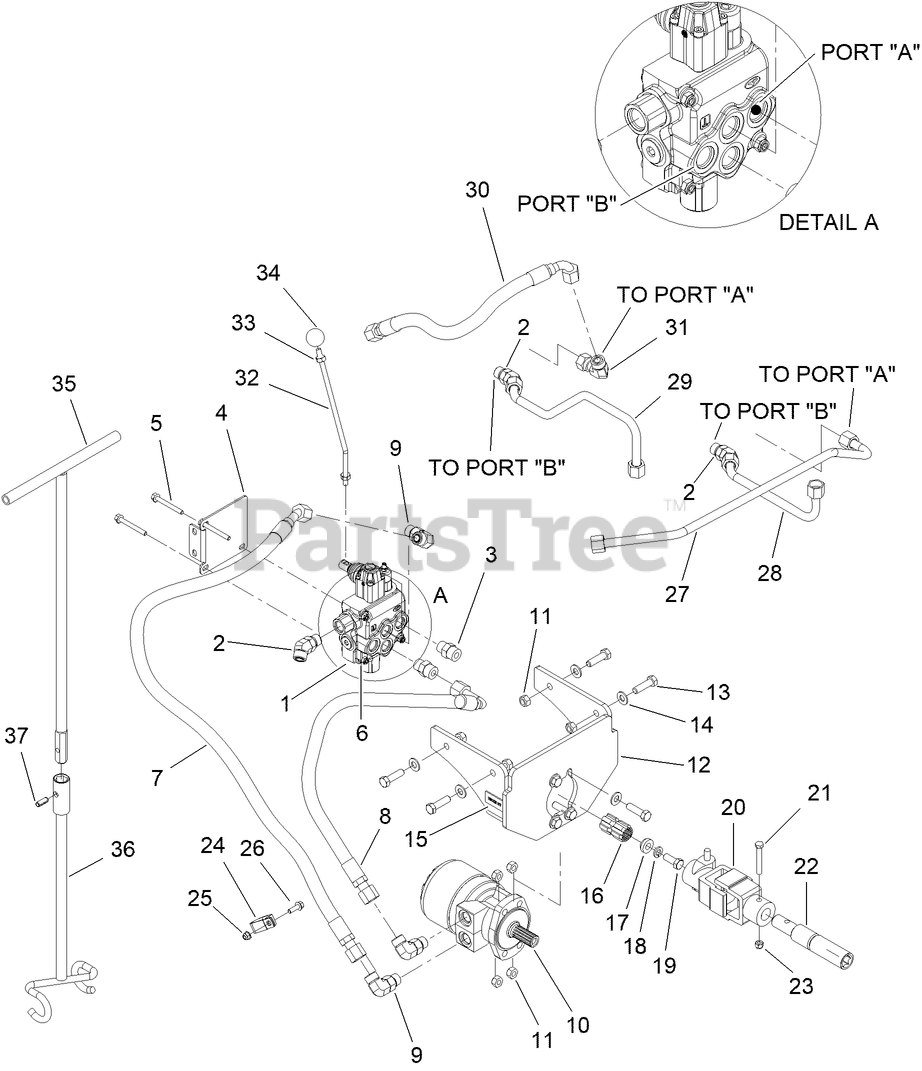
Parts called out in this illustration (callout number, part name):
1	HYDRO VALVE ASM
2	CONNECTOR (10S-10O45)
3	CONNECTOR (10S-10O)
4	BRACKET-HYDRO VALVE
5	SCREW-HHF
6	NUT-LOCK, NI
7	HOSE (10OFX45-53"-3000)
8	HOSE (10OFX90L-54"-3000)
9	CONNECTOR (10S-10O90)
10	HYD MOTOR ASM
11	LOCKNUT
12	MOUNT - HYDRABORE
13	SCREW-HH
14	WASHER-FLAT
15	HYDRABORE DECAL KIT
16	ADAPTER
17	RETAINER-ADAPTER
18	WASHER-LOCK
19	SCREW ( .50-20UNFX1.25 GRADE 8)
21	SCREW-HH
22	ADAPTER
23	NUT-HEX
24	CLAMP-R, DOUBLE
25	NUT-HF, NI
26	SCREW-HHF
27	HARDLINE (-10 HYDRABORER TO TRENCHER)
28	HARDLINE (-10 HYDRABORER TO RETURN)
29	HARDLINE (HYDRABORE TO RETURN)
30	HOSE (10OFX90S-18"-3000)
31	FITTING-HYD-90
34	KNOB-ROUND
35	HANDLE-TOOL, GUIDE
36	TOOL-GUIDE, ROD
37	PIN-ROLL
